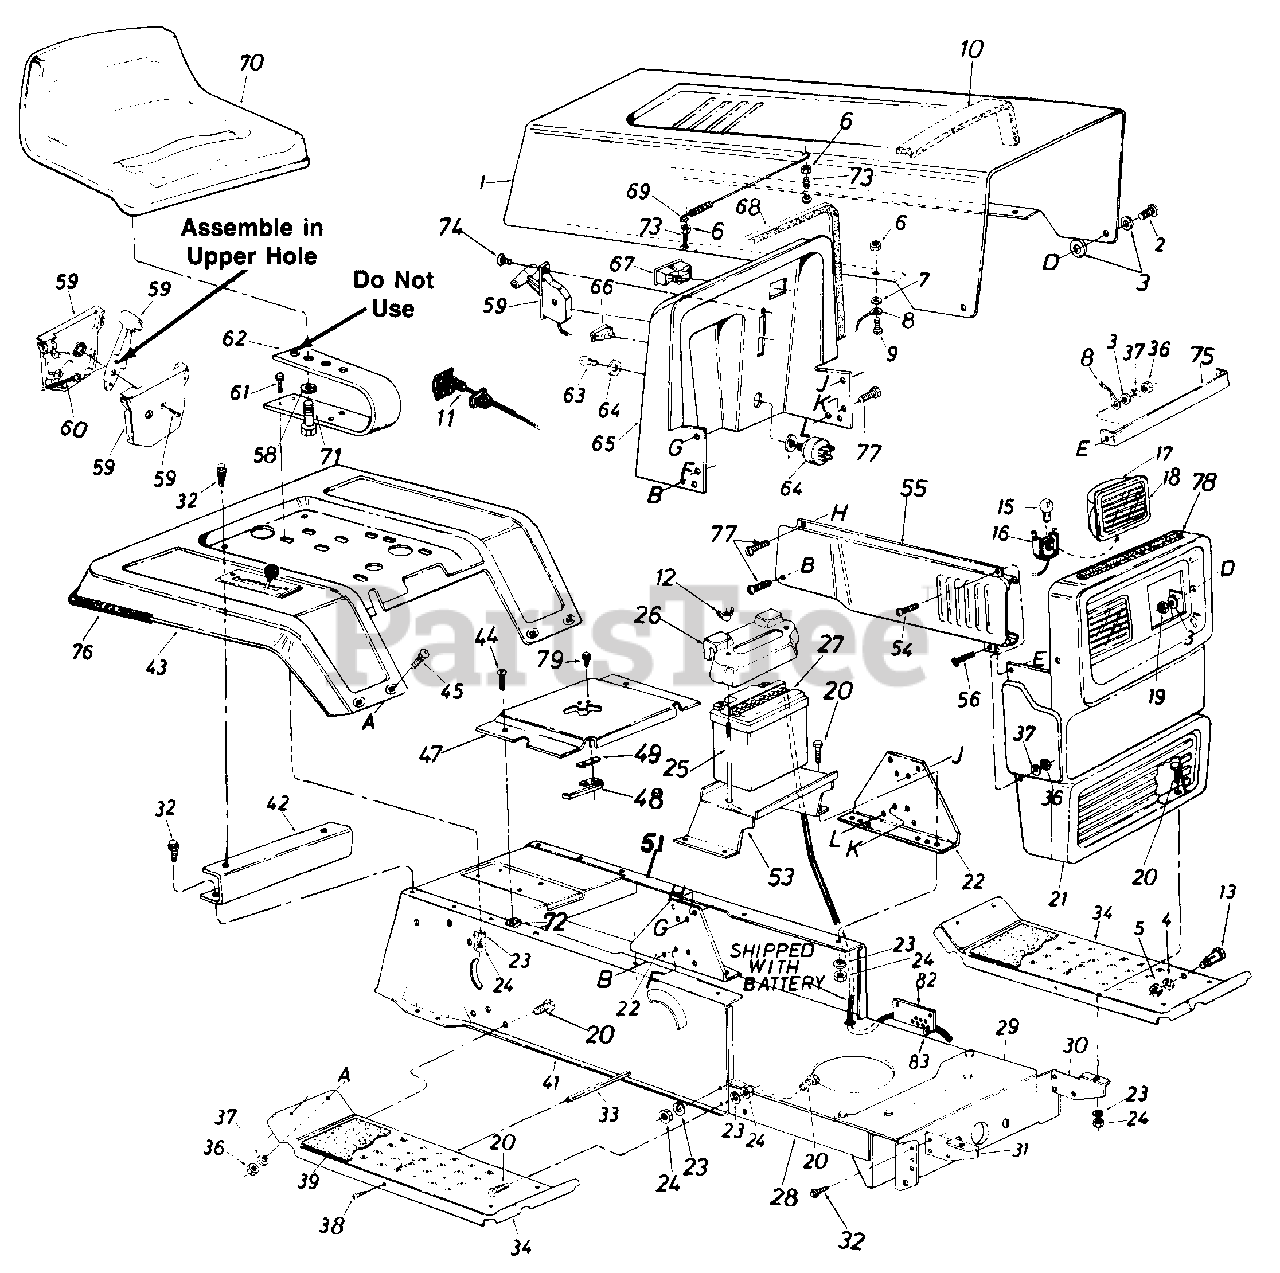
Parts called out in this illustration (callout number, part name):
1	Hood
2	Hex Scr. 1/4-20 x .62" Lg.
3	Fl-Wash. .296" I.D. x .62" O.D.
4	L-Wash. 3/8" I.D.
5	Hex Nut 3/8-16 Thd.
6	Hex Sems Nut #10-24 Thd.
7	Fl-Wash. .203" I.D. x .41" O.D. x .040
8	Hood Stop
9	Truss Hd. Scr. #10-24 x 1/2" Lg.
10	PVC Foam
11	Choke Control 44.0" Lg.
12	Wing Nut 1/4-20 Thd.-Plastic
13	Shld. Bolt .50" Dia. x .84
15	Lamp
16	Twist Lock-Lamp Socket
17	Headlight Housing
18	Lens
19	Hex L-Nut 1/4-2O Thd.
20	Hex Bolt 5/16-18 x .75" Lg.
21	Grille
22	Dash Support Bracket
23	L-Wash. 5/16" I.D.
24	Hex Nut 5/16-18 Thd.
25	Battery Hold Down Rod
26	Battery Cover
27	12 Volt Battery
28	Lower Frame
29	Front Pivot Brk't.
30	Grille Mount Brk't.-L.H.
33	Running Board Rod
34	Running Board
36	Hex Nut 1/4-20 Thd.
37	L-Wash. 1/4" I.D.
38	Truss Mach. Scr. 5/16-18 x .75" Lg.
39	Foot Pad
41	R.H. Side Frame
42	Fender Mount Brace
43	Rear Fender
44	Truss Mach. Tap Scr. #10 x .50" Lg.
45	Carriage Bolt 1/4-20 x .50" Lg.*
47	Transmission Panel
48	Reverse Safety Switch
49	Insulator Nut Plate
51	L.H. Side Frame
53	Battery Bracket
54	Truss Hd. Scr. 1/4-20 x .75" Lg.*
56	Truss Mach. Scr. 1/4-20 x .50" Lg.
58	L-Wash. 1/2" I.D.
59	Throttle Control Box Ass'y.
60	Throttle Control Wire 35"
61	Hex Bolt 5/16-18 x 1.0"
62	Seat Spring 5.5" High
63	Ignition Key
64	Ignition Switch
65	Dash Panel
66	Light Switch
67	Ammeter
68	Trim Strip-27"
69	Hood Spring
70	Seat Ass'y.
71	Hex Bolt 1/2-13 x 1.0" Lg.
72	Speed Nut #10Z
73	Hex Scr. #10-24 x 1.0" Lg.
74	Truss Mach. AB-Tap Scr. #10 x .5" Lg.
75	Tie Strap-Grille/Side Panel
76	Trim Strip-81"
77	Hex Wash. Hd. Tap Scr. 1/4 x .75" Lg.
78	Foam Strip 3/8 x 1-1/8 x 11/2" Lg.
79	Hex Wash. Hd. AB-Tap Scr. #8 x .50" Lg.
82	Brake Cable Bracket
83	Cable Tie
